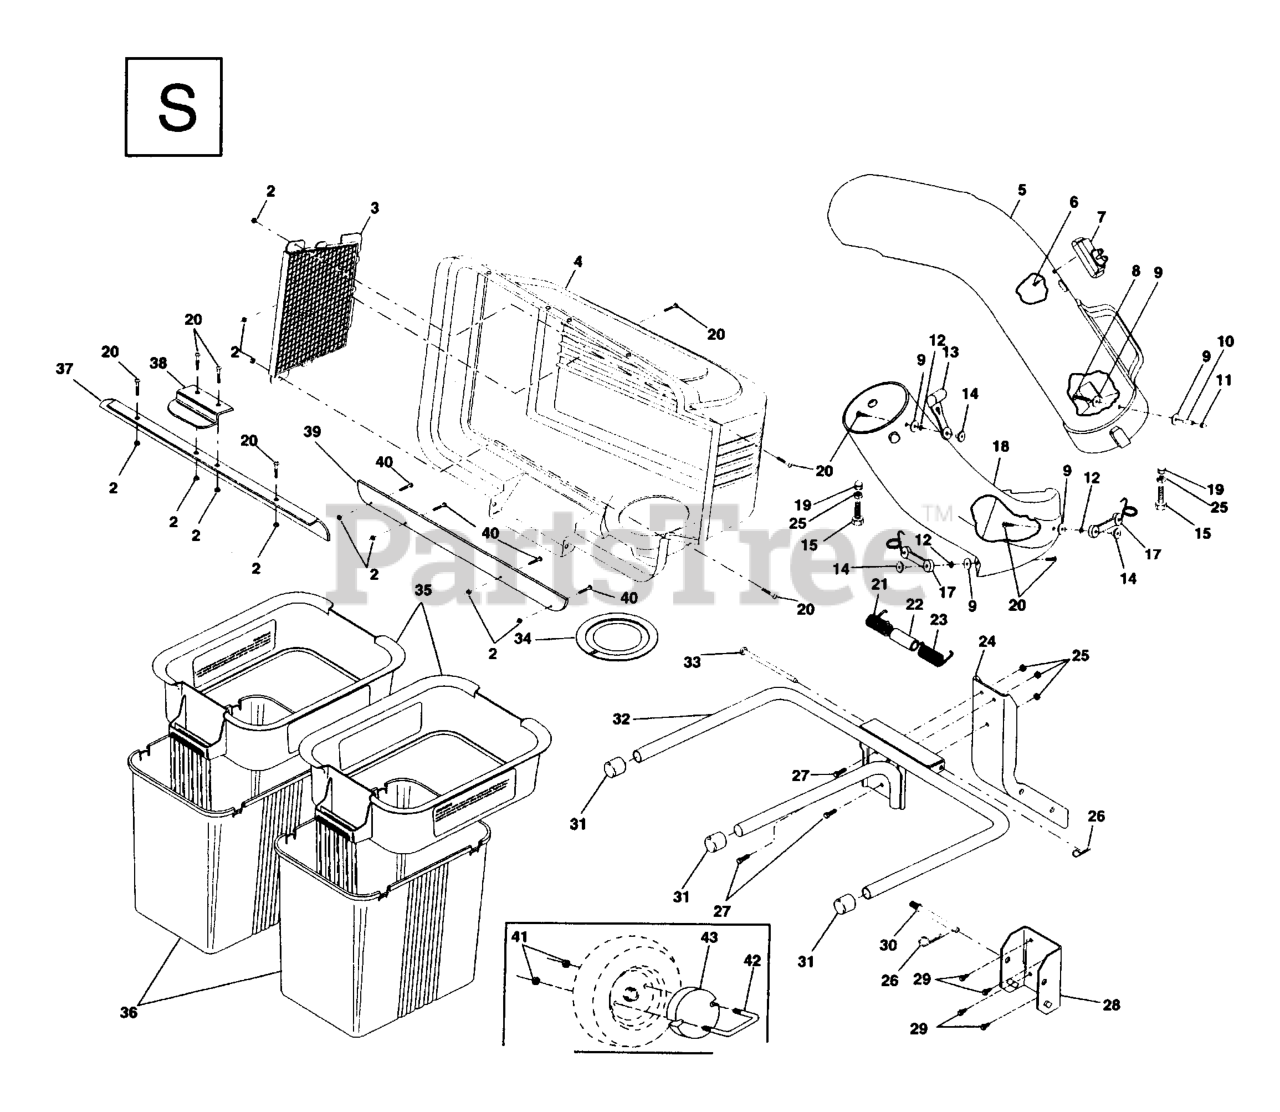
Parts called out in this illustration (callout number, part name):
3	COVER SCREEN
4	COVER BAGGER TOP
5	CHUTE.UPPER.BAGGER.36"
7	INDICATOR DUMP BAG
8	SCREW
9	WASHER
11	NUT
12	LOCKWASHER #10
13	LATCH.HOOD.
14	WELDNUT
15	BOLT GT
17	LATCH ASSEMBLY
18	CHUTE LOWER 36"
20	SCREW.10-24X5/8
21	SPRING COVER LH
22	SPACER.COVER.BAGGER
23	SPRING COVER RH
24	SUPPORT POST
26	RETAINER-SPRNG RB
27	BOLT
28	MTG BRACKET
29	Screw 5/16-18 x 1/2 Hex, Self Tapping 5/16-18 x 1/2
30	SUPPORT POST PIN
31	TUBING PLUG
32	BAGGER FRAME
33	HINGE PIN
34	GASKET.COVER.BAGGER
35	CONTAINER TOP
36	CONTAINER BOTTOM
37	SEAL.COVER.BAGGER
38	LATCH CER38
39	SEAL STRIP
40	SCREW
41	NUT
43	WEIGHT, FRT WHEEL
